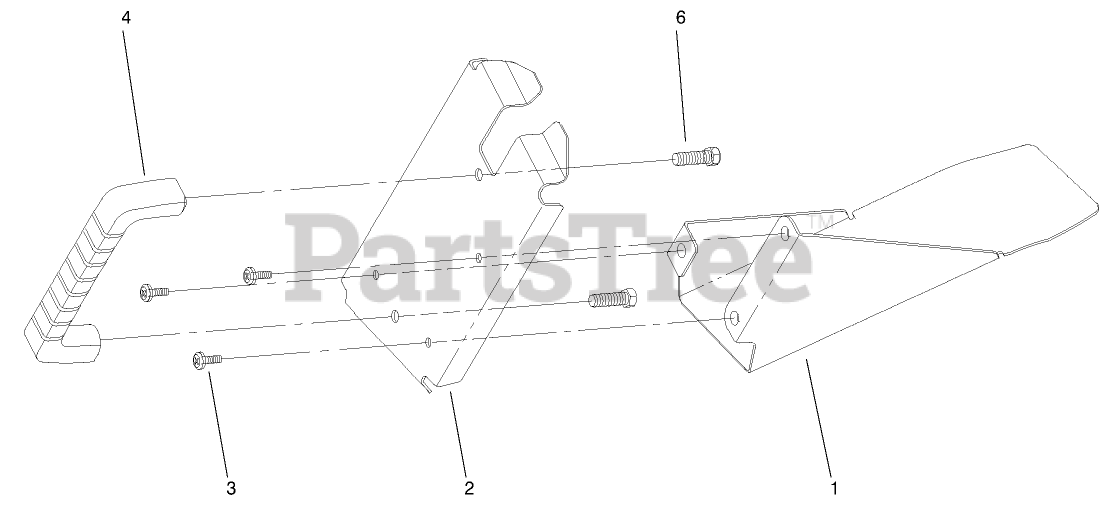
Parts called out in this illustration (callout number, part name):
1	SHIELD-DISCHARGE PLUG
2	COVER - DISCHARGE PLUG
4	HANDLE-DOOR
6	SCREW-HWH
